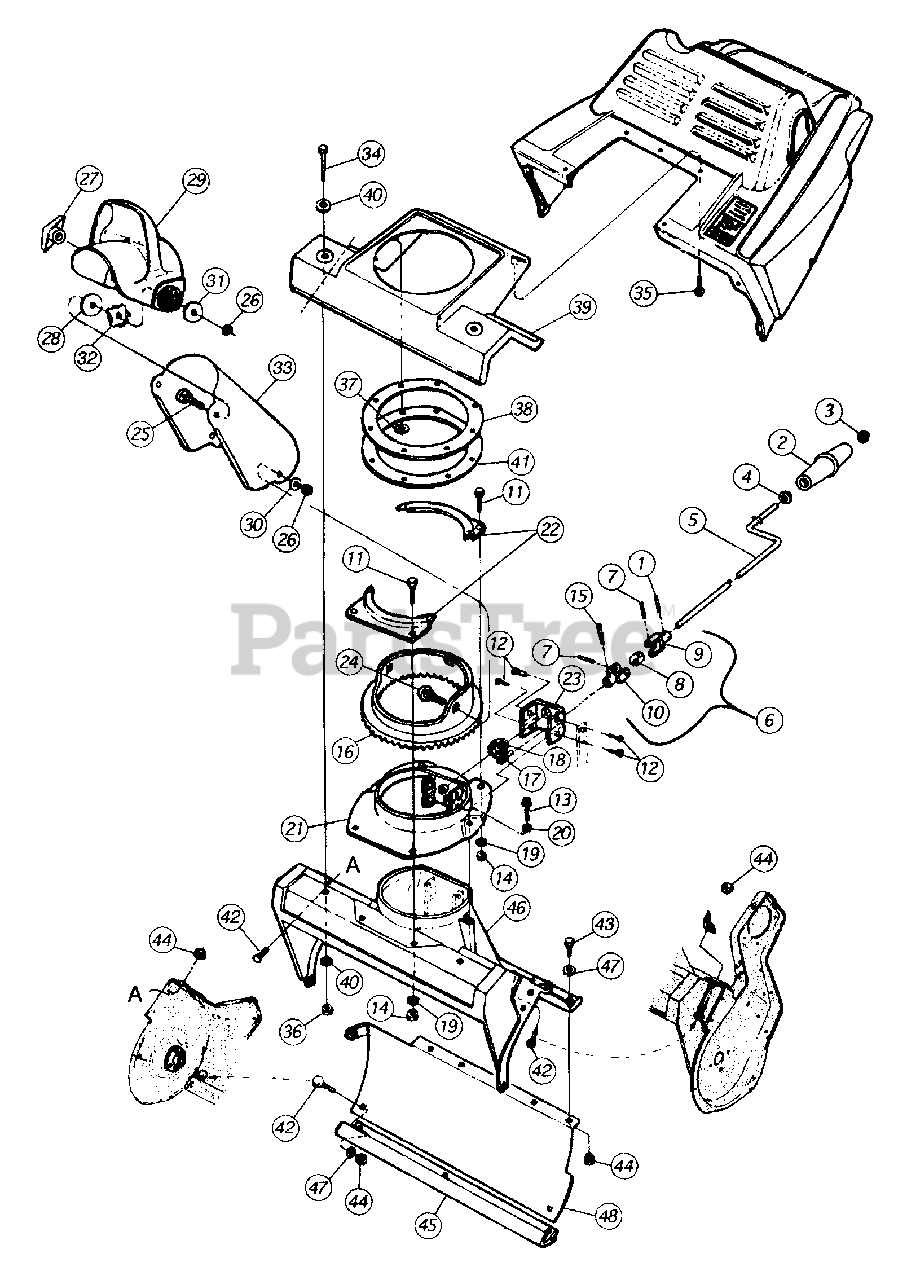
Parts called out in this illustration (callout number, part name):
1	Pin, Roll, 1/8 x .63
2	Knob, Chute Crank
3	Push Cap, 3/8 Rod
4	Washer, Flat, .385 x .62 x .06
5	Chute Crank
6	U-Joint Assembly, Complete
7	Pin, Roll, 5/32 x .88
8	Connector, U-Joint
9	Clevis, Rear U-Joint
10	Clevis, Front U-Joint
11	Screw, Hex Cap 1/4-20 x .75 GR5
12	Screw, Hex Wash Hd Tapp 1/4 x .5
13	Screw, Hex Wash Hd Tapp #12-14 x 1.0
14	Nut, Hex Sems, 1/4-20
15	Pin, Cotter, 1/8 x 1.24
16	Chute Base, Black
17	Gear, Chute Drive
18	Gear, Chute Idler
19	Washer, Flat, .28 x .74 x .063
20	Washer, Flat, .218 x .62 x .063
21	Plate, Chute Base
22	Retainer, Chute Base
23	Bracket, Gear Mounting
24	Carriage Bolt
25	Carriage Bolt, 5/16-18 x 1.0
26	Nut, Hex Insert Lock, 5/16-18
27	Knob, Wing Nut, 5/16-18
28	Washer, Rubber, .50 x 1.5 x .08
29	Chute Deflector (Yellow)
30	Washer, Flat, 5/16 ID
31	Washer, Flat, .35 x 1.59 x .062
32	Washer, Octagon
35	Screw, Wash Hd Tapp #10-16 x .62
36	Nut, Hex Sems, 1/4-20
37	Speed Nut, Push On
38	Chute Gasket
39	Chute Base Cover
40	Washer, Flat, .28 x .74 x .063
41	Retainer Gasket
42	Carriage Bolt, 1/4-20 x .75
43	Screw, Hex Cap 14-20 x .75 GR5
44	Nut, Hex Sems, 1/4-20
45	Shave Plate
46	Auger Housing (Yellow)
47	Washer, Flat, .25 x .62
